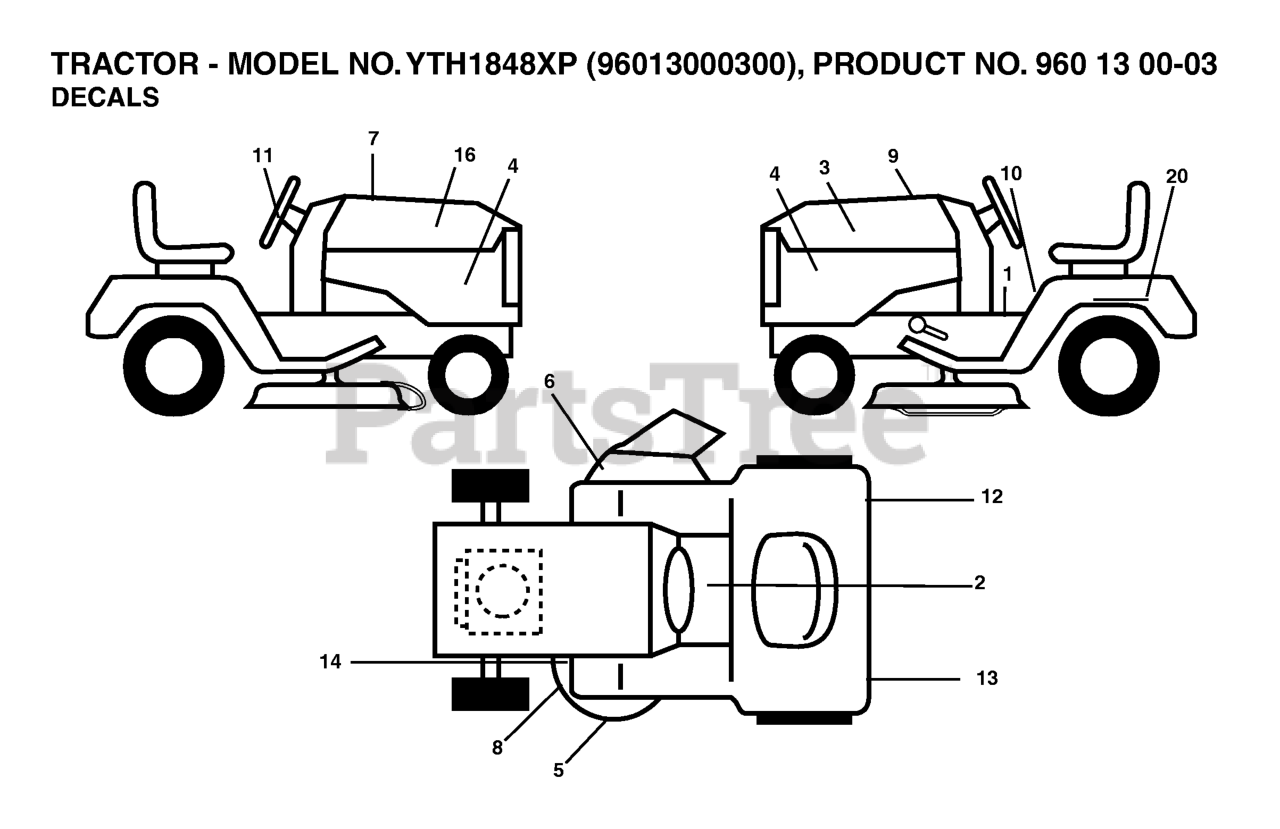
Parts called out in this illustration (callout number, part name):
6	DECAL.WARN.KEEP.HAND.AWAY
7	DECAL HOOD CUST. RESP.
8	DECAL CLUTCH/BRAKE
10	DECAL FENDER DANGER
11	DECAL.STEERING.HUSQ.BLUE
20	DECAL BTRY SYMBOLS
